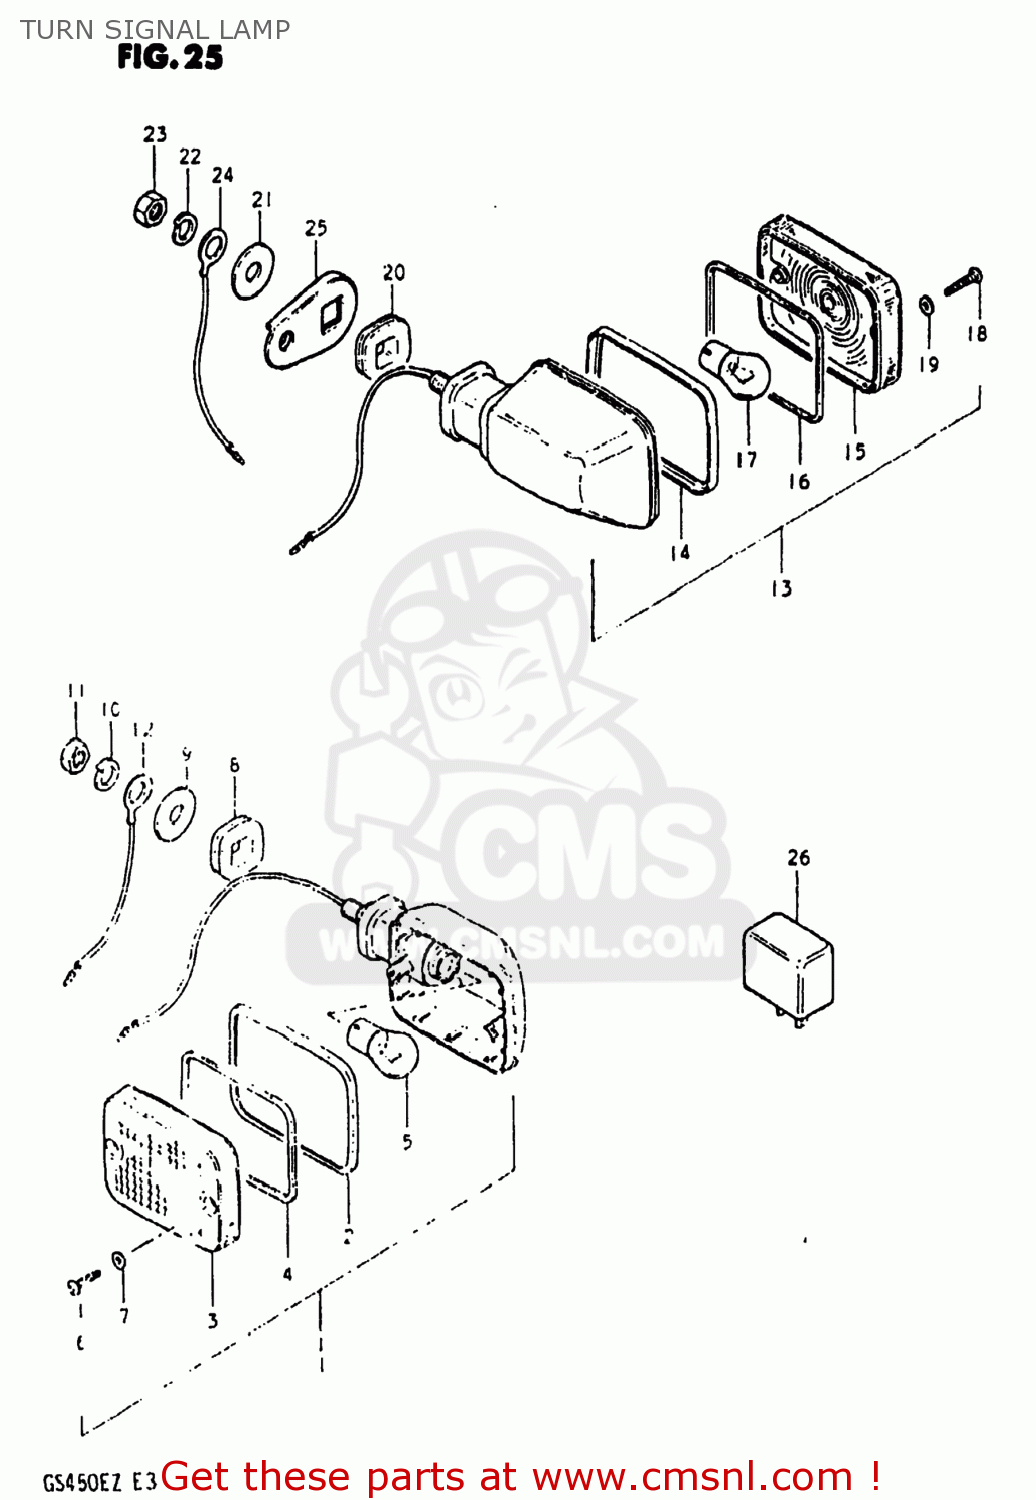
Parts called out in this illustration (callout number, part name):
1	LAMP ASSEMBLY,FRONT TURN SIGNAL
2	RIM
3	LENS
4	GASKET (NAS)
5	BULB(12V23W,STANLEY,A4577A)
6	SCREW
7	GASKET (NAS)
8	CUSHION
9	WASHER (10.5X30X2.3)
10	LOCK WASHER
11	NUT
12	LEAD WIRE,EARTH
13	LAMP ASSEMBLY,FRONT TURN SIGNAL
14	RIM
15	LENS
16	GASKET (NAS)
17	BULB(12V23W,STANLEY,A4577A)
18	SCREW
19	GASKET (NAS)
20	CUSHION
21	WASHER (10.5X30X2.3)
22	LOCK WASHER
23	NUT
24	LEAD WIRE,EARTH
25	BRACKET,RR TURN SIGNAL LAMP
26	RELAY,TURN SIGNAL
